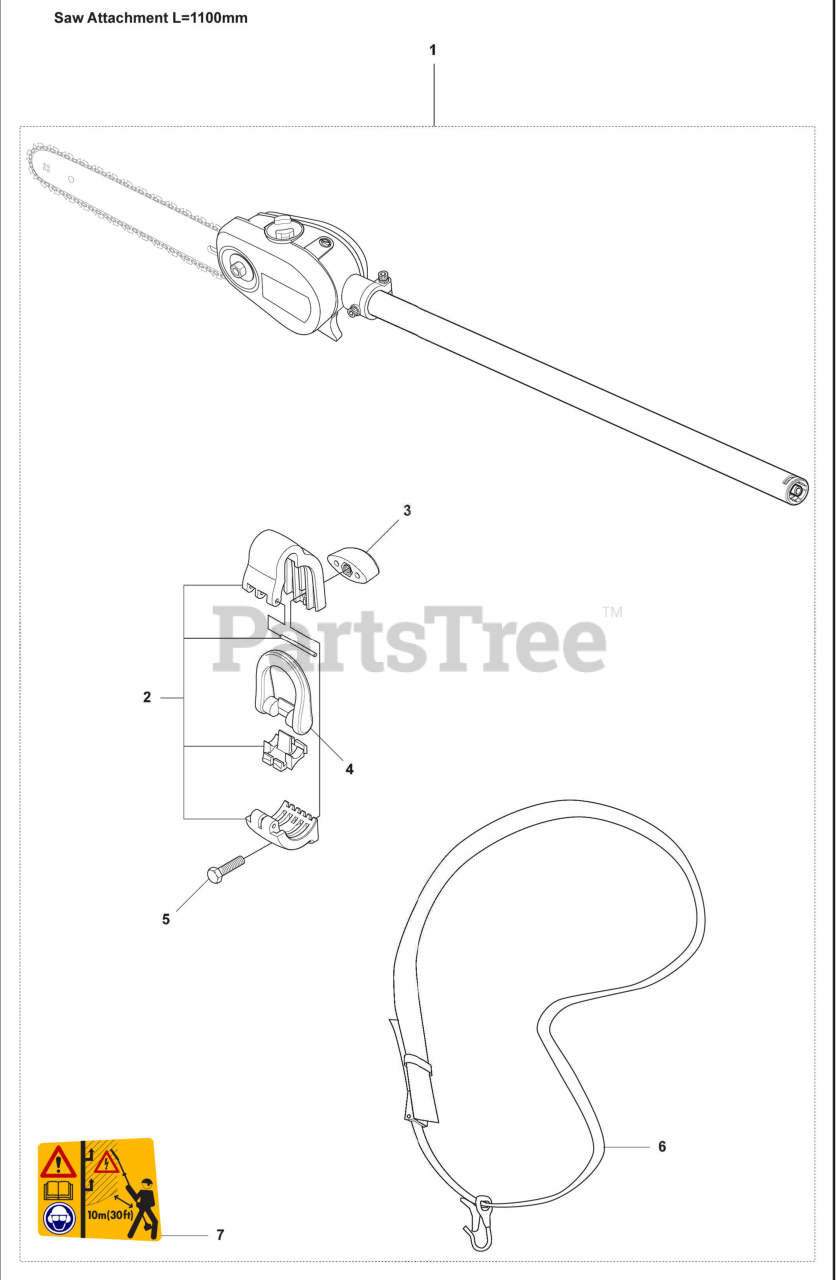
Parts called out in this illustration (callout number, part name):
1	DX POLE SAW ATTACHMEN
1	Dx Pole Saw Attachment
2	Hanging Bracket
5	Screw, M6S 5 X 20
6	Shoulder Strap with Sign
7	Decal
